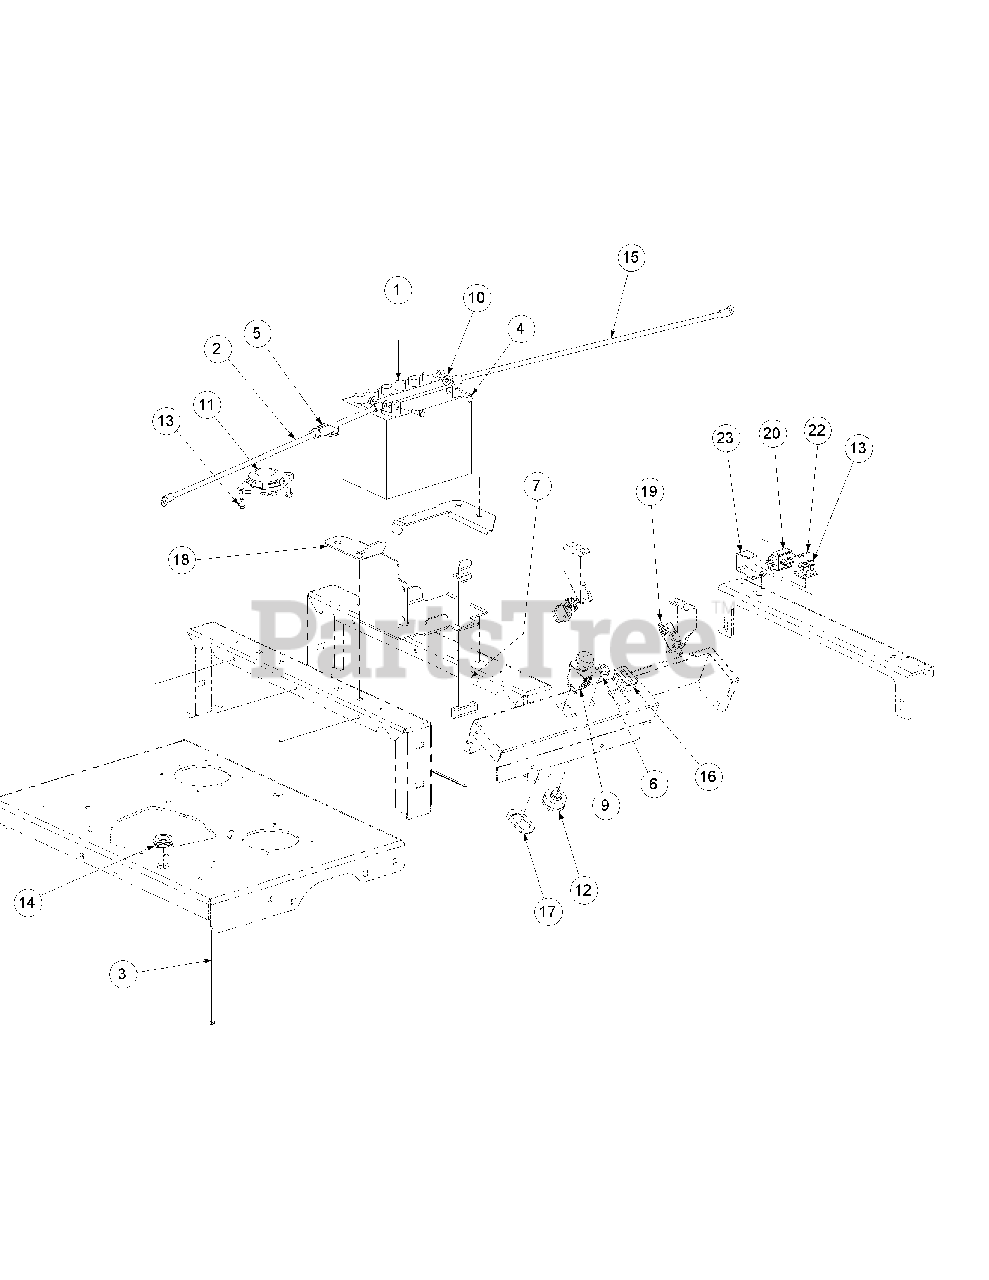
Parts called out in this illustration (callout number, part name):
2	Cable, Battery, Red, 36"
3	Tie, Cable, 3/16 x .05 x 7.4"
4	Screw, Hex, Cap, 1/4-20 x .75
5	Boot, 1" OD Rubber Battery-PST, Red
6	Nut, W/Cap, 5/8-32 Ignition
7	Strap, Battery
9	Switch, Electric, PTO
10	Nut, 1/4-20, Hex Flange Lock Nut
11	Switch, Seat N/C
12	Switch, Ignition, 6 Pin
13	Screw, TT, 1/4-20 x .5, Hex Index Washer
14	Grommet, .75 ID
15	Cable, Battery Black, 28"
16	Meter, Hour
17	Bracket, PTO Switch Retainer
18	Mount Bracket, Battery
19	Switch, Safety
20	Switch, Plunger
22	Switch Bracket Mount
23	Switch Clamp
